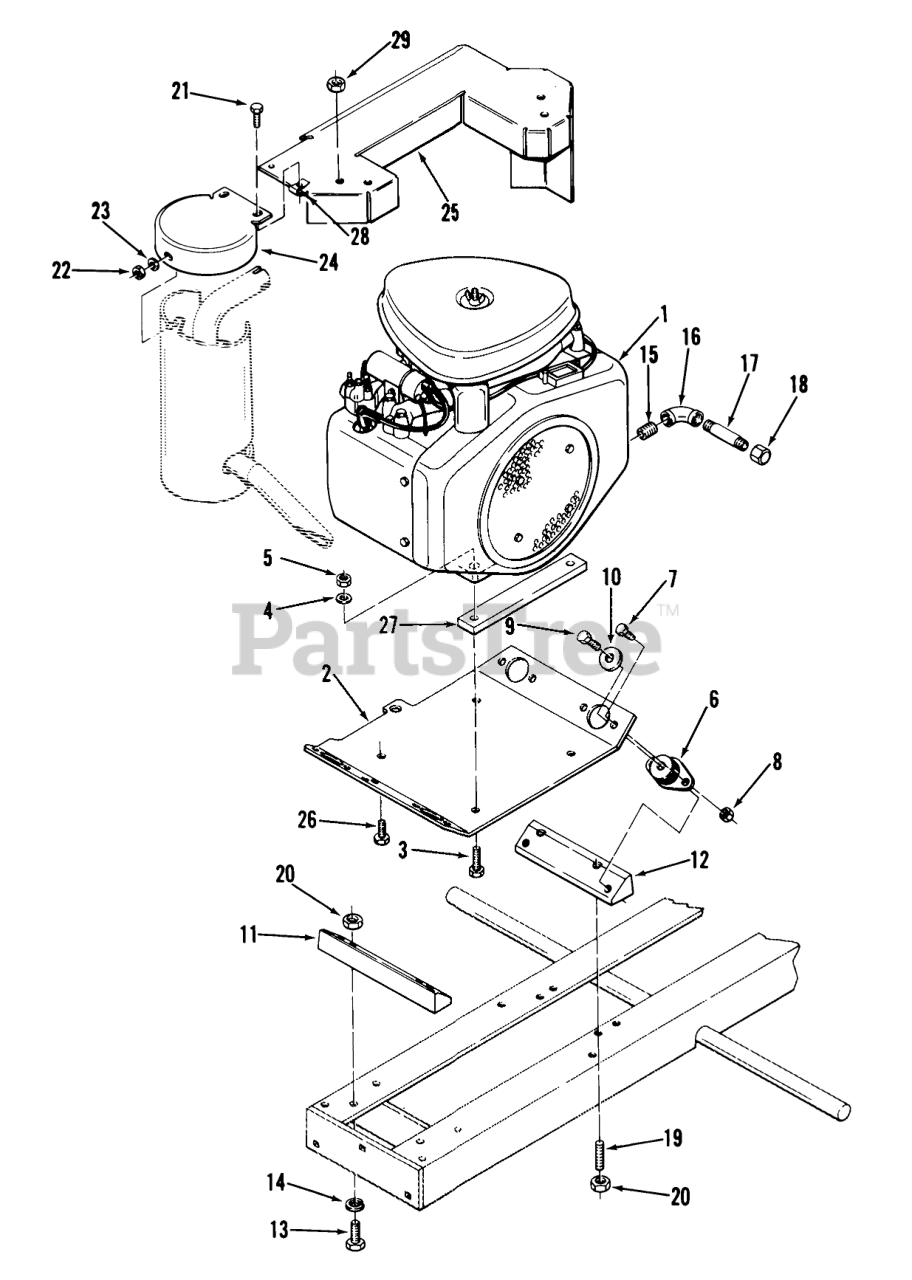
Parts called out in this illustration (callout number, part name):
1	Engine 17 HP Kohler KT-17 Spec PS-24125A
2	Engine Cradle
3	Bolt 3/8-16 x 1 1/2 Special
4	Washer
5	Nut
6	MOUNT-ISOLATION
7	H H C S
8	Nut
9	Bolt
10	Washer
11	Engine Mounting Block-Front
12	MOUNT BLOCK-REAR
13	BOLT
14	LOCKWASHER
15	Nipple 3/8
16	Elbow 3/8
17	Nipple 3/8 x 4 1/2
18	Cap
19	SET SRW 3/8X16-1 3/4
20	Nut
21	Screw
21	H H C S
22	Nut
24	CAP-MUFFLER SHIELD
25	Heat Shield
26	BOLT
27	Spacer
29	Flanged Nut
